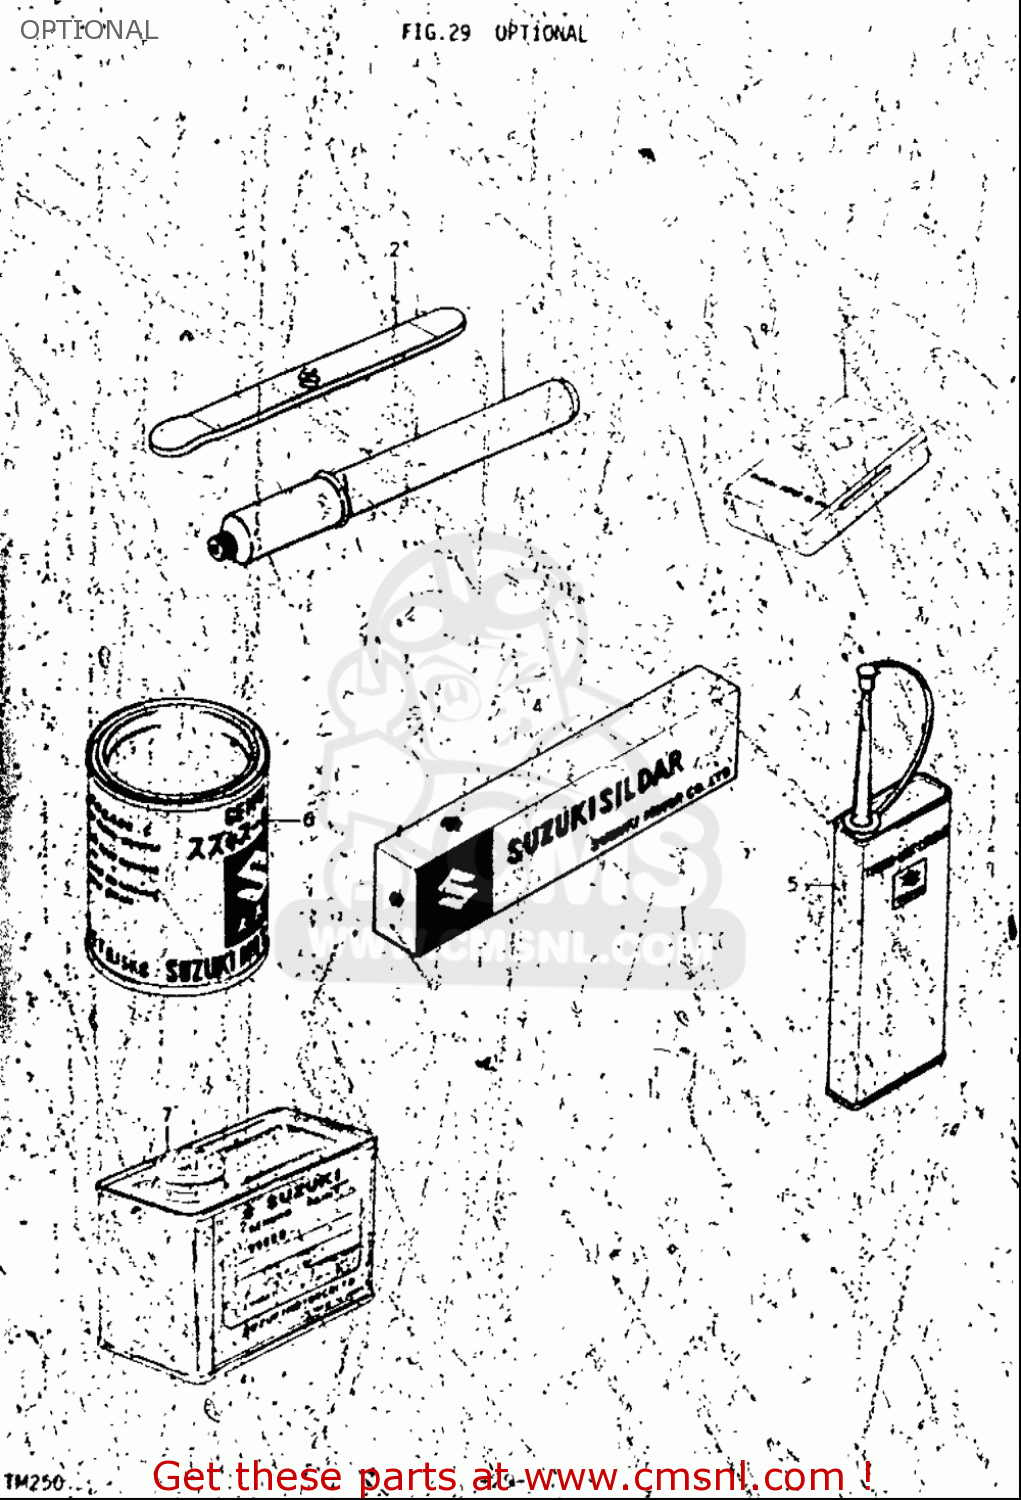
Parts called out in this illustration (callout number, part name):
2	LEVER,TIRE
5	THREAD LOCK NO.1401 CLEAR 200G
6	GREASE(C)EP2 LITHIUM 150G
